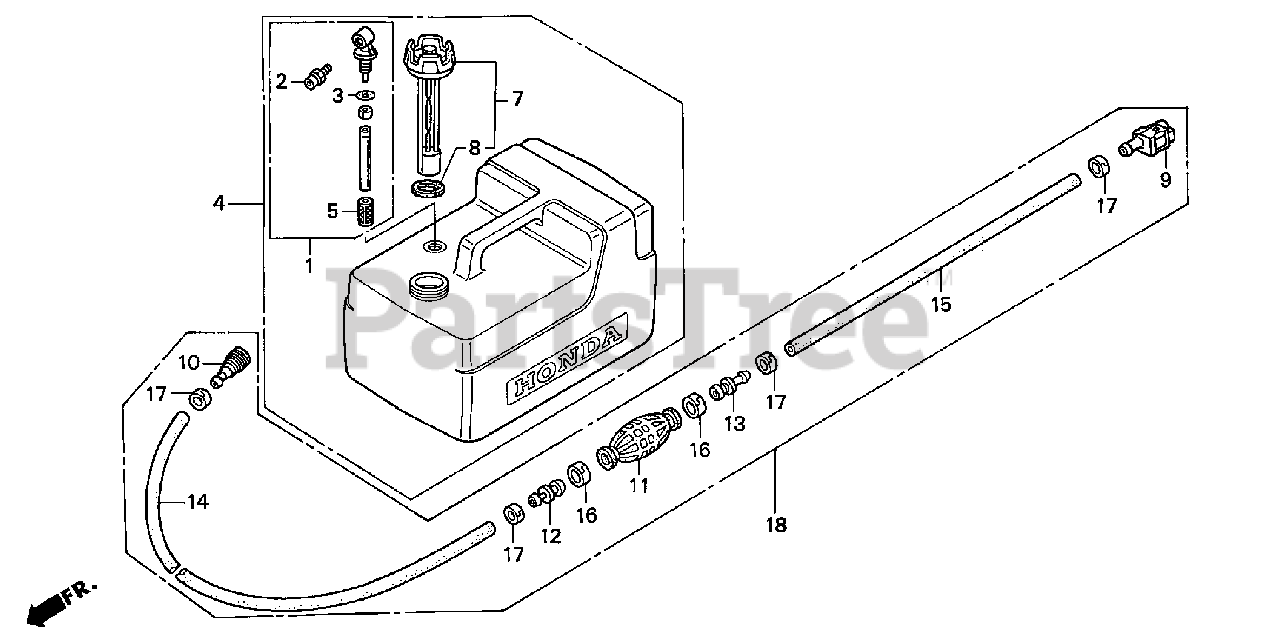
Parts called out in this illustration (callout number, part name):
1	JOINT ASSY., FUEL
2	FITTING, QUICK DISCONNECT
3	O-RING
4	TANK ASSY., FUEL
5	FILTER, FUEL
7	CAP, FUEL FILLER
8	GASKET, FUEL CAP
9	CONNECTOR ASSY., FUEL (A)
10	CONNECTOR, FUEL
11	PRIMER BULB
12	VALVE, IN.
13	VALVE, OUTLET
14	TUBE, FUEL (7.5X2000)
15	TUBE, FUEL SHORT
16	BAND, TUBE CLIP (20MM)
17	BAND, TUBE CLIP (12.5MM)
18	TUBE ASSY., FUEL
